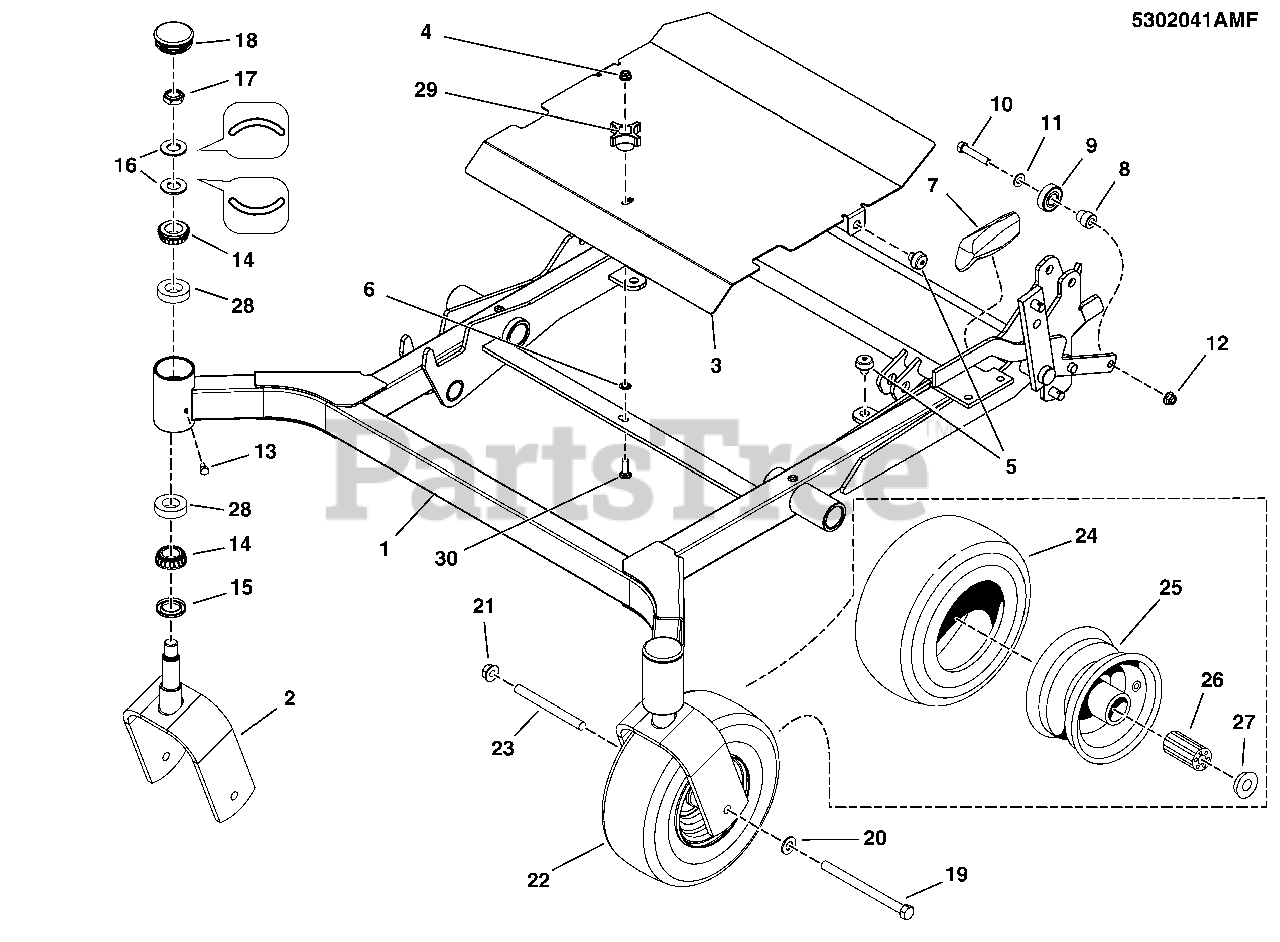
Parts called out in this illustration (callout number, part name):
1	WELD, MOWER FRAME, 800, 72 - RED
2	WELD, FRONT CASTER YOKES - RED
3	DECK GUARD, CENTER, 800, 72 - RED
4	NUT, 5/16-18 HEX NYLOCK FLANGE
5	MNT, VBRTN, RBBR
6	NUT, Push On, 5/16
7	GRIP, BLACK FLEXIBLE
8	SPACER, HYDRO PULLEY
9	BEARING, BALL 11/16X1-9/16X15/32
10	BOLT, 3/8-16 X 2 GD5 YZ
11	WASHER, 3/8 SAE
12	NUT, 3/8-16 HEX NYLOCK FLANGE
13	BOLT, 1/4-28 X 1/2, GD5 YZ
14	BEARING, TAPERED ROLLER, 1
15	SEAL, GREASE
16	WASHER, BELLEVILLE - 1.500 X .755
17	NUT, 3/4-16, HEX JAM NYLON LOCK
18	CAP, LOW PROFILE, STEEL
19	BOLT, 1/2-13 X 6-1/2 GD5 YZ
20	WASHER, 1/2 SAE
21	NUT, 1/2-13 HEX NYLOCK FLANGE
22	WHEEL, CASTER, 11 X 4.0-5 SILVER BEAD LO
23	CASTER AXLE DDSH
24	TIRE, FRONT, 11 X 4.0 - 5 (SV)
25	WHEEL ASSEMBLY, 11 X 4.0 - 5 TIRE CMP (SV)
26	BEARING, CASTER WHEEL, 11 X 4.0 - 5 BEAD LOCK (SV)
27	BEARING, RETAINER (SV)
28	CUP, BEARING (SV)
29	KNOB-INT THR .312-18 4-ARM 2.12WD 1.06 LG
30	BOLT, 5/16-18 X 1, CARRIAGE
